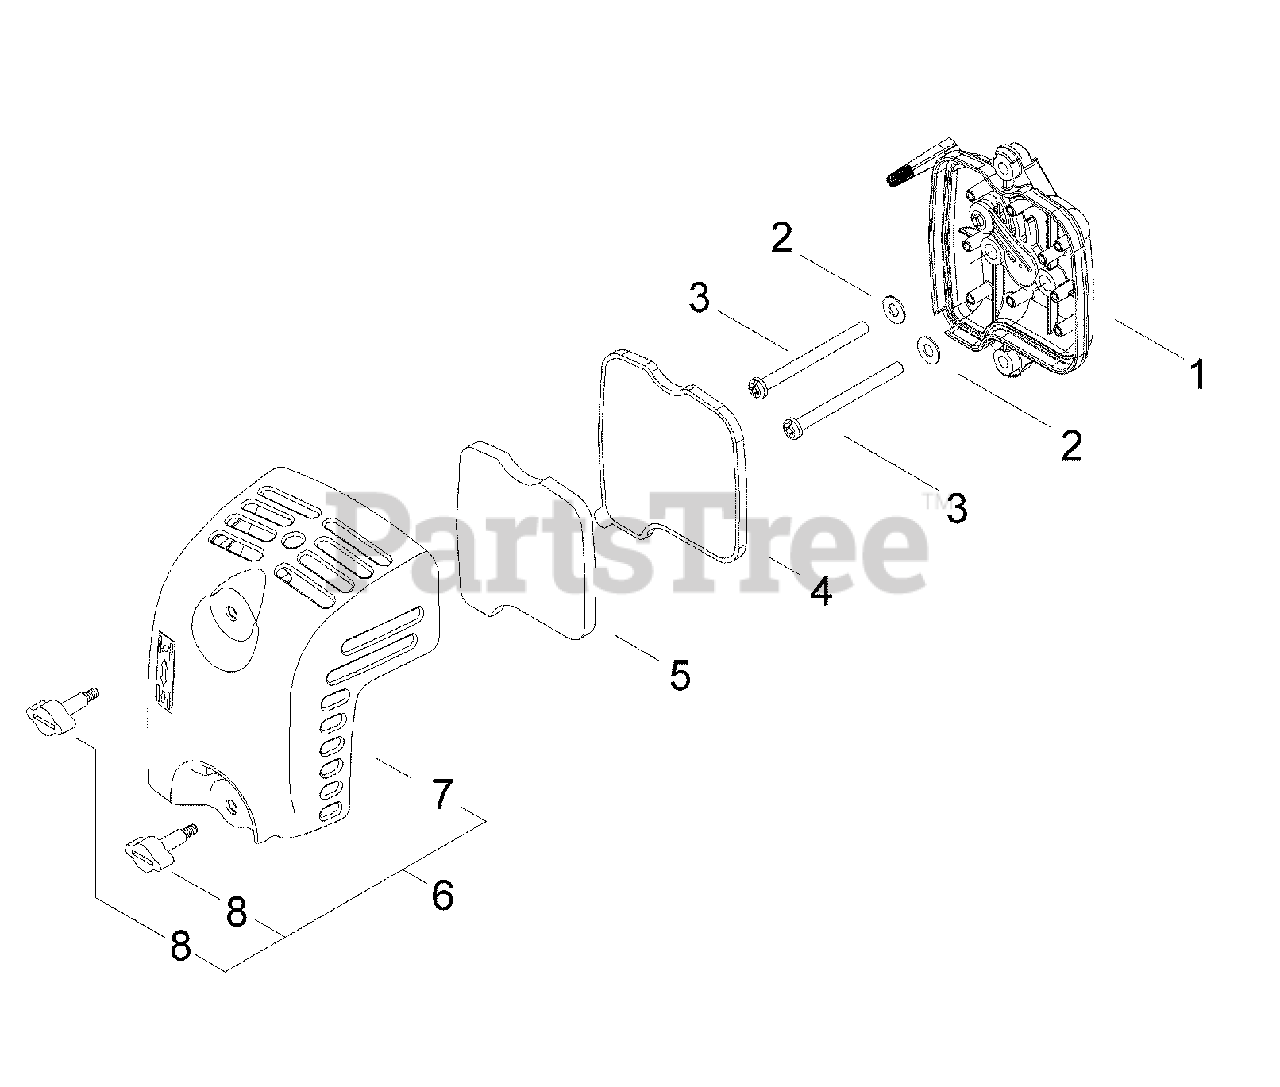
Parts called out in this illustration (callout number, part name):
1	CASE ASSY, AIR FILTER
2	WASHER 5 MM
3	SCREW M5×60
4	FILTER, AIR
5	PRE-FILTER, FOAM
6	COVER ASSY, AIR FILTER
7	COVER, AIR FILTER
8	THUMBSCREW M5
